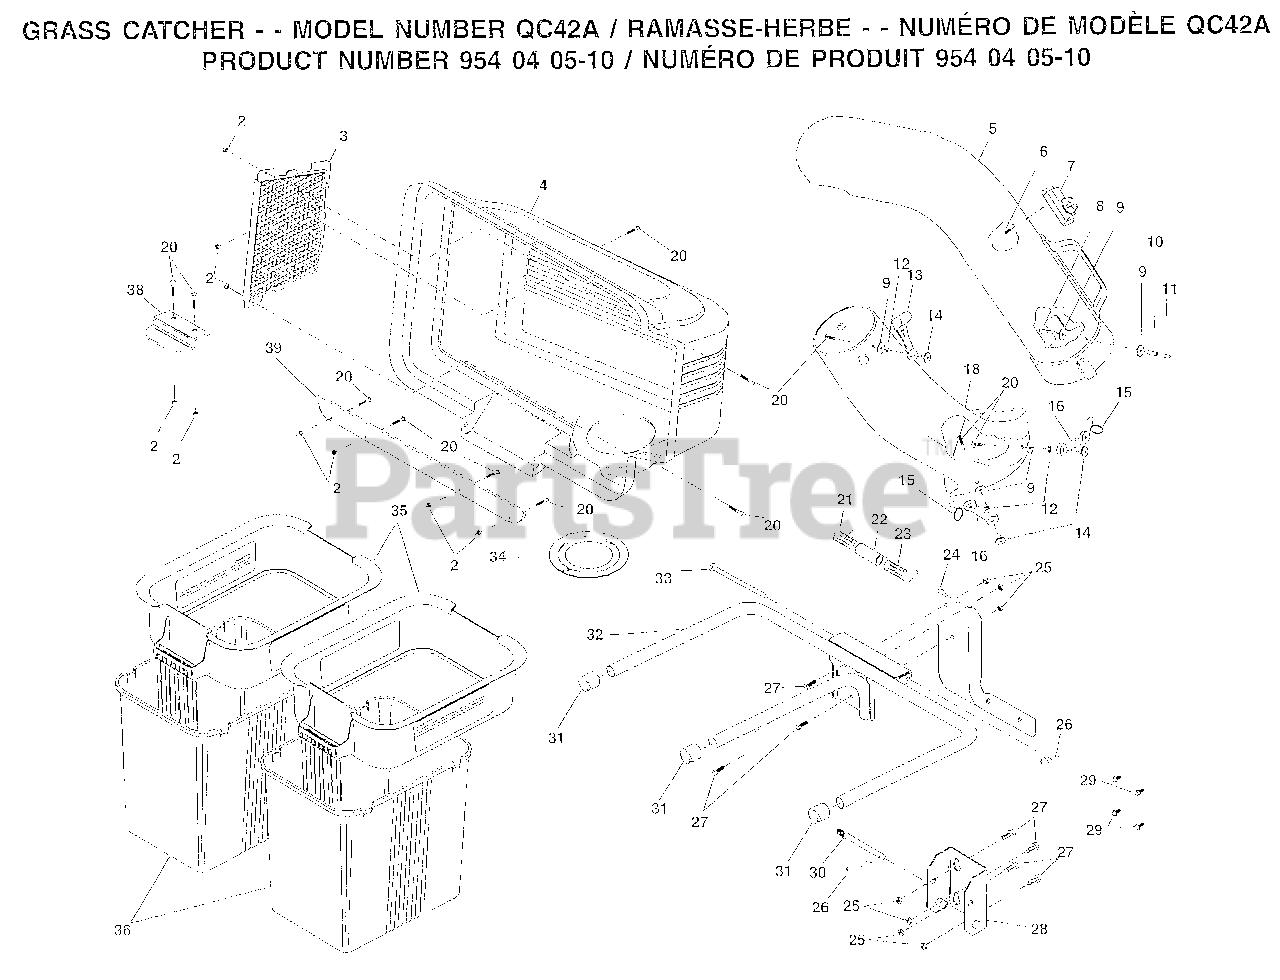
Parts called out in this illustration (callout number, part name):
2	NUT, CROWNLOCK #10-24
6	SCREW, SPECIAL #10-14X1/2
9	WASHER 3/16X3/4X16 GA
18	CHUTE, LOWER
20	SCREW#10-24 X 5/8
27	BOLT, HEX 5/16-18 X 3/4
28	BRACKET, MOUNTING
29	BOLT SHOULDER
39	STRIP.REINFORCEMENT
